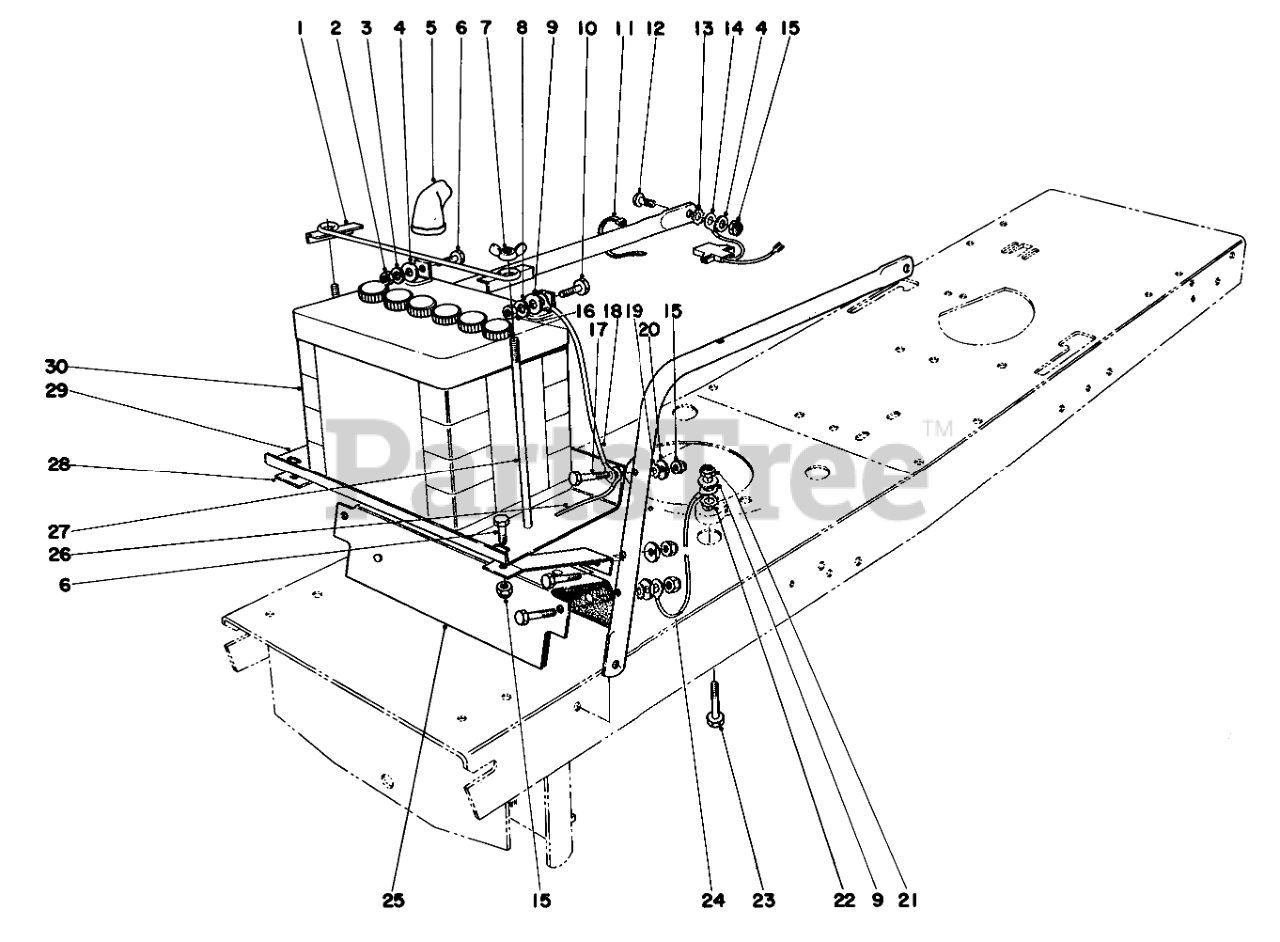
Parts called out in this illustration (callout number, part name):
1	Battery Clamp
2	NUT-HEX
3	WASHER-LOCK
4	WASHER-FLAT
5	BATTERY BOOT
6	SCREW-HH
7	WING NUT
8	WASHER-LOCK
9	WASHER-PLAIN
10	SCREW-HH
11	Cable Tie
12	BOLT-CARR
13	WASHER-LOCK/EXT
14	Wire Receptacle Assembly
16	NUT-HEX
17	SCREW-HH
18	Wire Assembly Battery to Ground
19	WASHER-LOCK/EXT
20	WASHER
21	NUT-LOCK, CONE
22	WASHER-LOCK
23	SCREW-HH
24	Wire Assembly Engine to Ground
25	Heat Shield
26	Wire Assembly Headlight to Ground
27	BATTERY BOLT
28	Brace Battery Shelf
29	Battery Shelf
30	Battery
